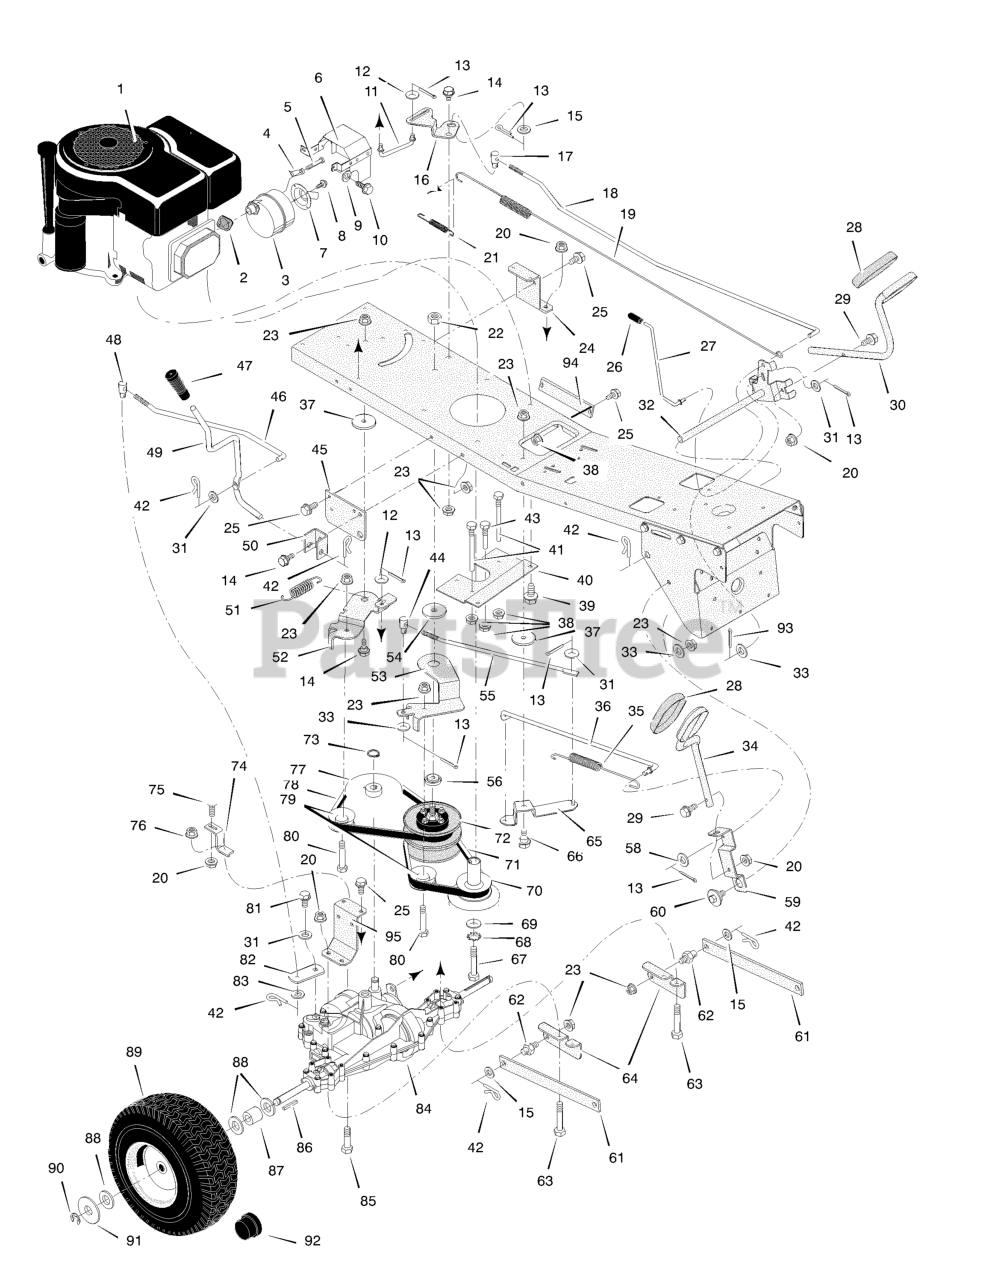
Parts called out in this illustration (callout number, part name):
1	Engine
2	GASKET, Exhaust
3	Muffler
4	Lock, Muffler Screw
5	Bolt, Hex
6	Shield, Heat
7	Tube, Exhaust
9	Washer, Lock
10	Screw
11	Rod, Link
13	Pin, Cotter
14	Bolt, Shoulder
15	Washer
16	Link, Clutch
17	NUT, Adjusting, 1/2-13
18	Rod, Clutch Variator
19	Spring, Brake
20	Nut
21	Spring, Brake Return
23	Nut
24	Bracket, Transaxle -Left
27	Rod, Parking Brake
28	Pad, Pedal
29	Bolt, Hex
30	Rod, Clutch/Brake
32	Rod, Clutch/Brake Pivot
33	Washer
34	Pedal, Variator
35	Spring, Return
36	Rod, Variator Connect
38	Nut
39	Screw
40	Plate, Belt Guide
41	Guide, Belt -Long
42	Pin, Hair
43	Guide, Belt -Short
44	Nut, Adjusting
45	Bracket, Lift Pivot
46	Rod, Shift Link
47	Grip
48	Nut, Adjusting
49	Lever, Shift
50	Bracket, Pivot
51	Spring - Variator Drive
52	Arm, Idler
53	Arm, Clutch Ider
55	Link, Drive
58	Washer
59	Arm, Pedal
60	Bolt, Shoulder
62	Pin, Threaded
63	Bolt, Hex
64	Bracket, Rear Hanger
65	Link Assembly, Pivot
66	Bolt, Shoulder
67	Bolt, Hex
68	Lockwasher
70	Pulley Stack
71	Belt, Primary Drive
72	Pulley Assembly, Variator
73	Ring, Snap
74	Bracket, Torque Reactor
75	Bolt, Carriage
76	Nut, Stoverlock
77	Pulley, Transaxle
78	Belt, Secondary Drive
79	Pulley, Idler
80	Bolt, Hex
81	Cap Screw
82	Yoke, Shift
84	Transaxle
85	Bolt, Hex
86	Key, Square
87	SPACER, Rear Wheel
89	Wheel & Tire Assembly
92	Hub Cap
93	Pin, Cotter
94	Plate, Reinforecement
95	Bracket, Transaxle -Right
